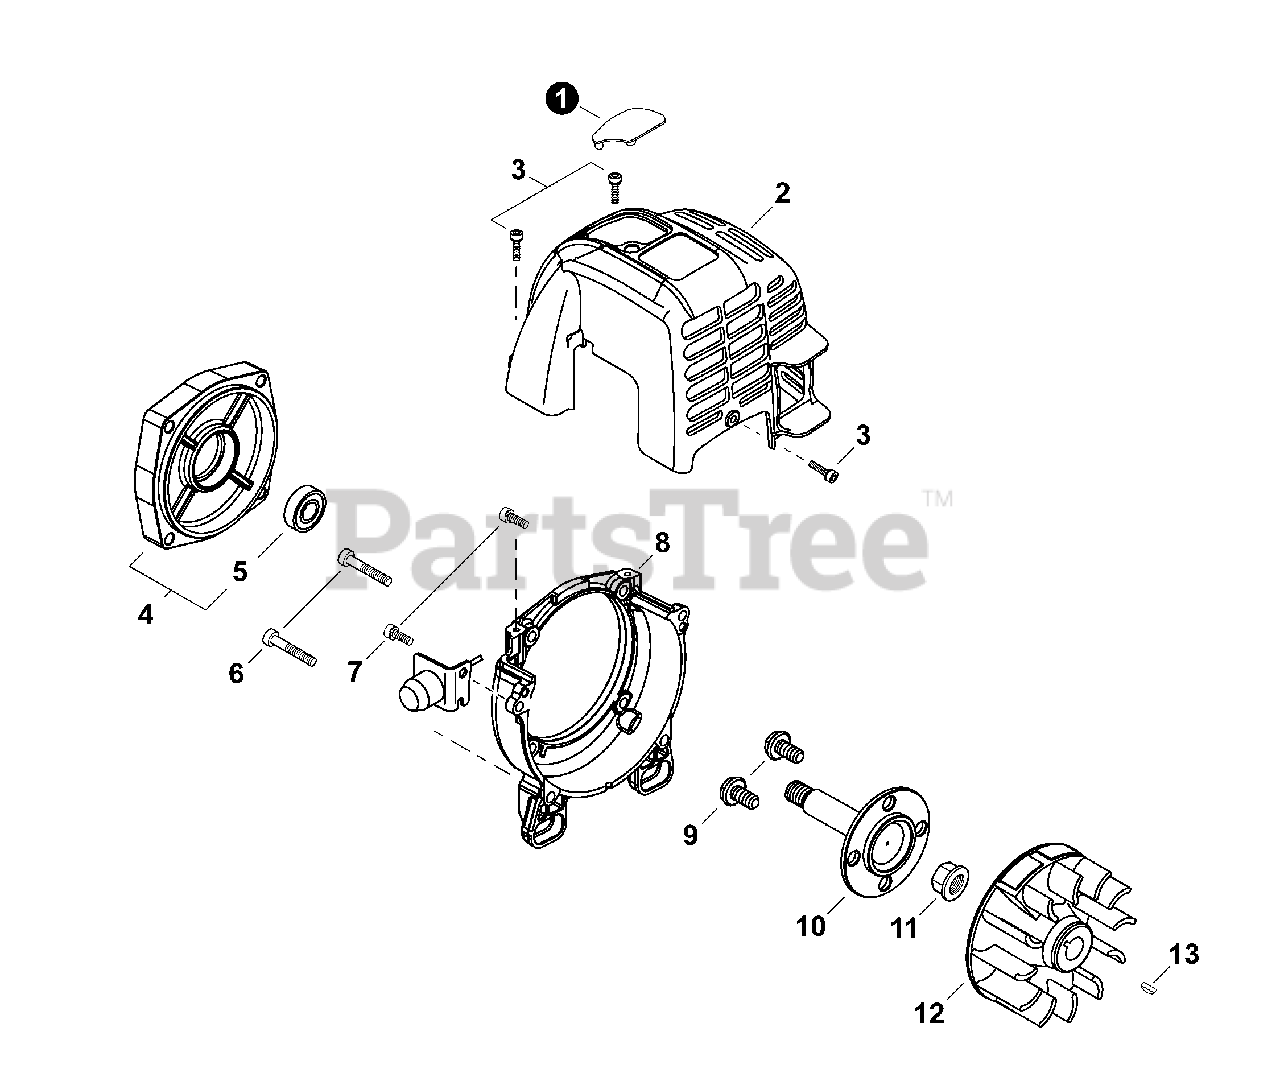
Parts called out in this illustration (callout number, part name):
1	COVER, SPARK PLUG
2	COVER, ENGINE
3	BOLT M4×14
4	ADAPTOR SET, PUMP
5	BEARING, BALL 6002
6	BOLT 5×30
7	BOLT 5×16
8	COVER, FAN
9	BOLT, FLANGE M8×16
10	SHAFT, PUMP
11	NUT, CRANKSHAFT M8
12	FLYWHEEL Ø95
13	KEY, WOODRUFF 3×10
